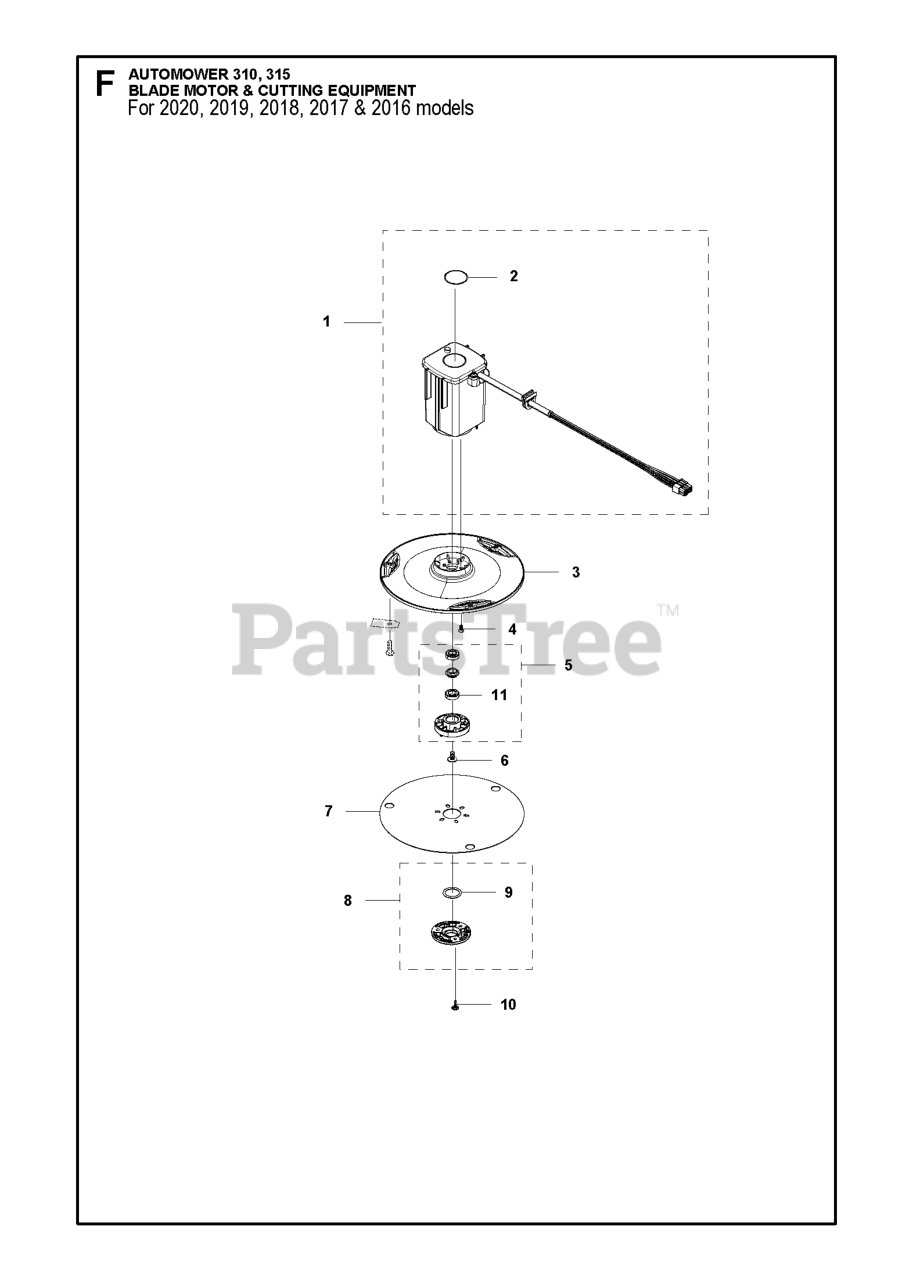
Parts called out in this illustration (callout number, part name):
1	MOTOR ASSY
2	KIT AIR FILTER KIT 305 - 10 PC
3	CUTTING DISC CUTTING WIDTH 22
4	SCREW HEXAGON SOCKET BUTTON HE
5	BEARING HOUSING ASSY
6	SCREW
7	SKID PLATE
8	COVER KIT BEARING
9	O-RING 20X2,5 MM
10	SCREW 14MM
11	BALL BEARING 2 RS,TIGHT CLEAR
11	BALL BEARING BALL BEARING 535
